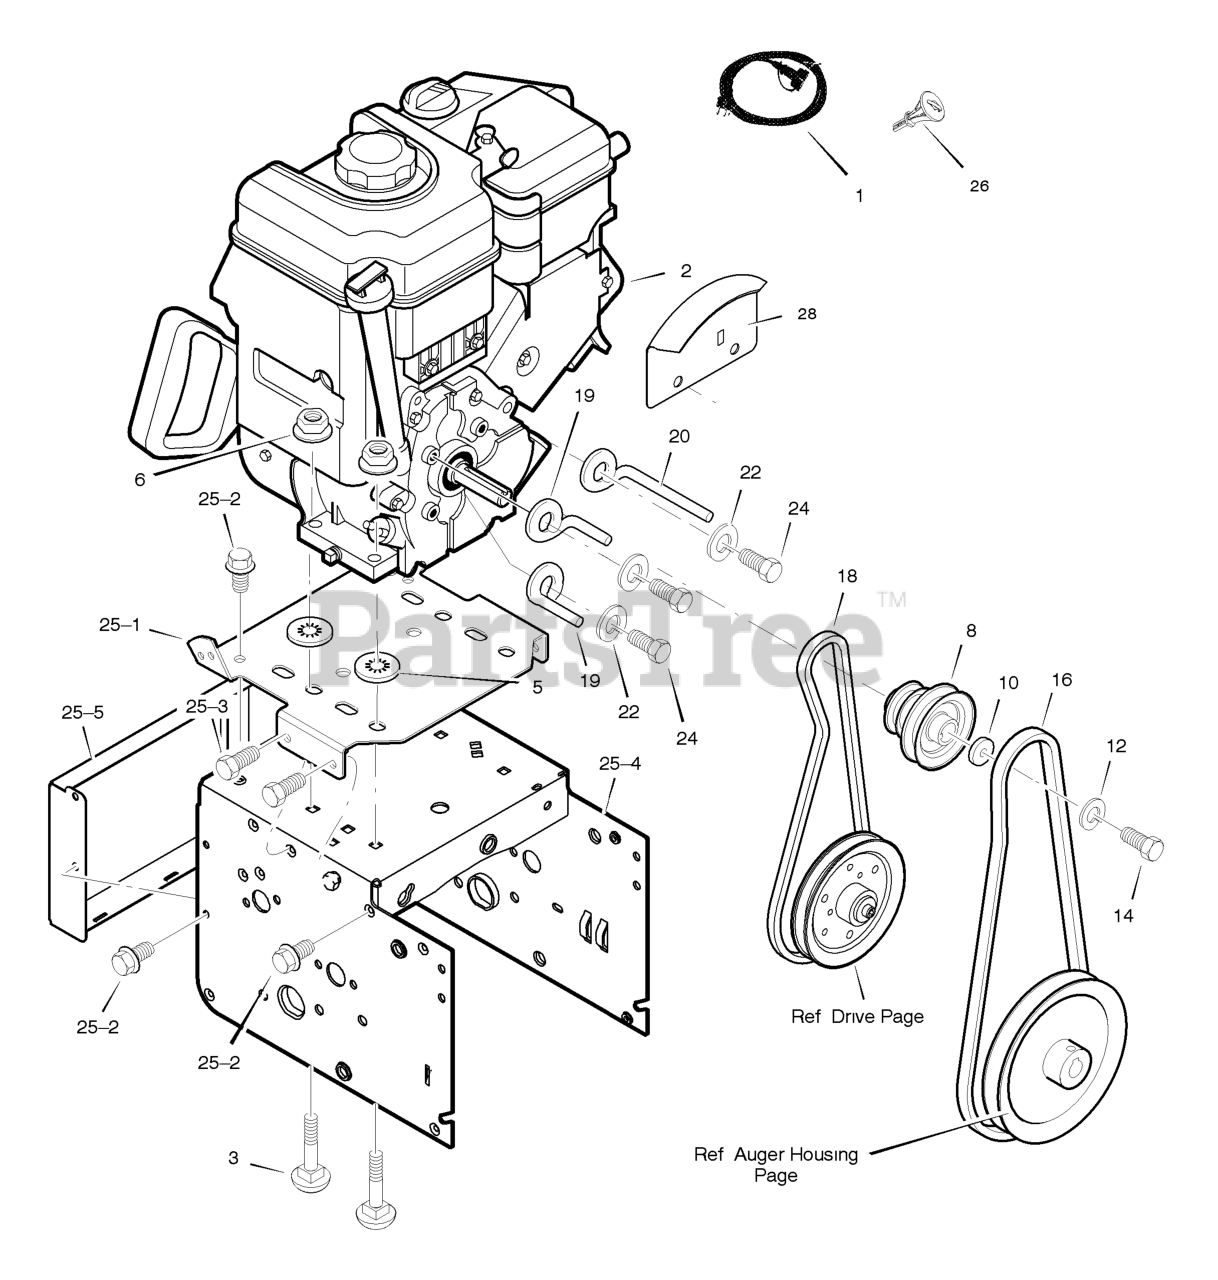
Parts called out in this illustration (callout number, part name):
1	CORD, Electric, 10FT. 110V
2	ENGINE
3	BOLT, CARRIAGE 5/16-18
5	RETAINER, PUSH
6	NUT 5/16-18
8	PULLEY, ENGINE
10	WASHER
12	WASHER
14	SCREW, 3/8-24 x 1.00
16	BELT, HYDRO DRIVE
18	BELT, V
19	GUIDE, ROD BELT
20	GUIDE, ROD BELT
22	WASHER, SPTLK .31X.58X.08
24	SCREW, 5/16-24 x 1.00
25	FRAME ASSEMBLY
25-1	PLATE, ENGINE MOUNT
25-2	SCREW 1/4-20 X .63
25-3	SCREW 5/16-18 X .50
25-4	FRAME, MOTOR BOX
25-5	PANEL, BACK
26	KEY, BRIGGS ENGINE
28	SHIELD, BRIGGS ENGINE
